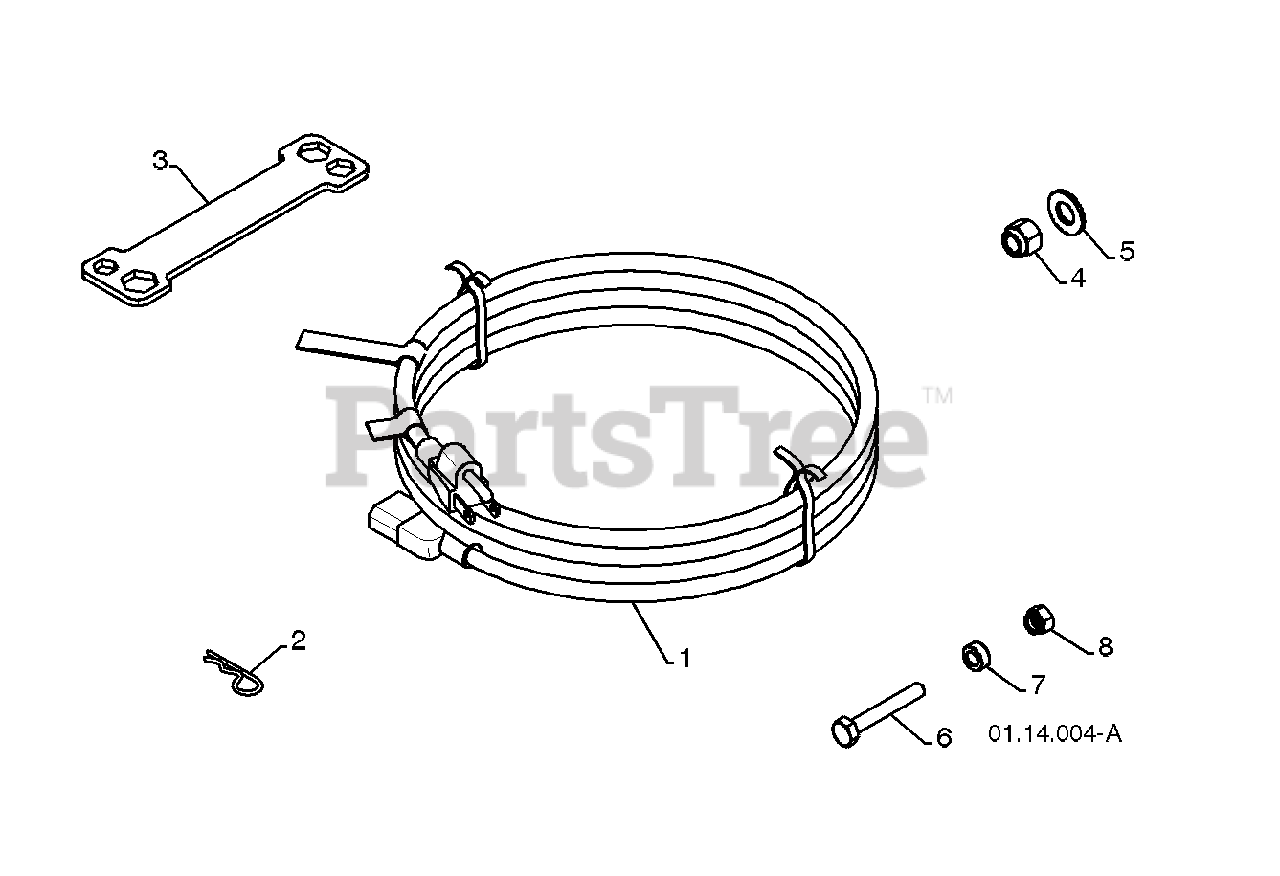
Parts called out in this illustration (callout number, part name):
1	POWER CORD
2	RETAINER PIN
3	WRENCH
4	LOCKNUT 3/8-16
5	WASHER 3/8
6	SHEAR BOLT 1/4-20 X 1-3/4
8	LOCKNUT 1/4-20
